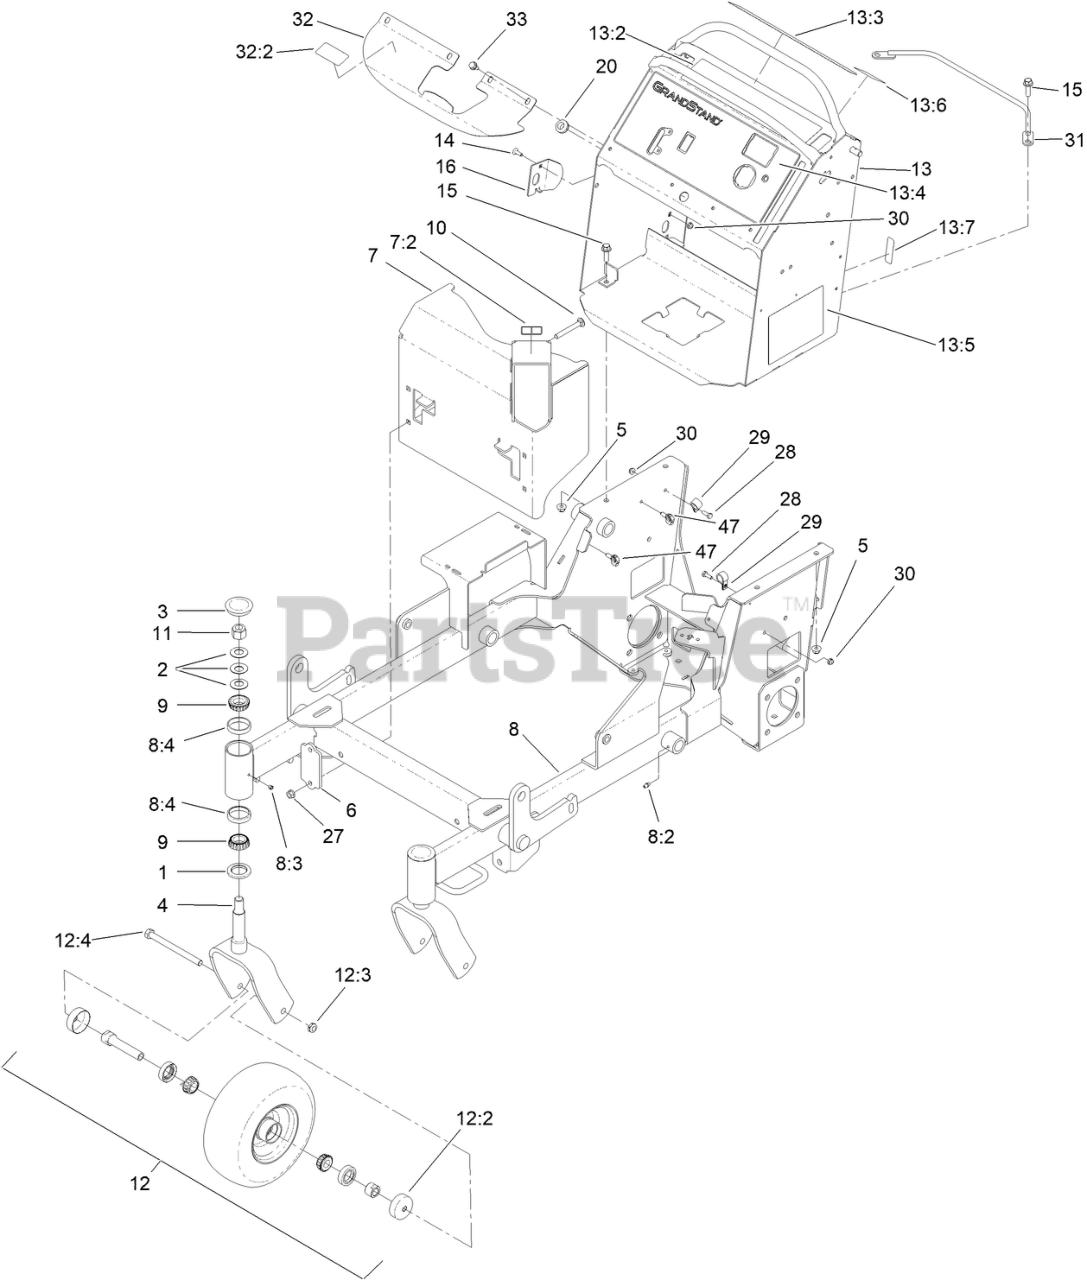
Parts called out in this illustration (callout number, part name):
1	SEAL-GREASE
2	WASHER-BELLVILLE
3	CAP-GREASE
4	FORK-CASTER
5	NUT-HF, NI
6	BRACKET-MOUNTING, GUARD
7	MUFFLER GUARD ASM
7:2	DECAL-WARNING
8	FRAME ASM
8:2	FITTING-GREASE
8:4	CUP-BEARING
9	BEARING-ROLLER, TAPERED
10	SCREW-CARR
11	NUT-LOCK, NI
12	WHEEL, TIRE AND BEARING ASM
12:2	GUARD-SEAL
12:3	NUT-HEX
12:4	SCREW-HH
13	TOWER - DECAL ASM
13:2	DECAL-OPC
13:3	DECAL-WARNING
13:4	DECAL - PANEL, CONTROL
13:5	DECAL-SERVICE AID, CE
13:6	DECAL-STABILITY, CE
13:7	DECAL - FUSE
14	BOLT-CARR
15	SCREW-HHF
16	PLATE-STRIKER
20	GROMMET
27	NUT-HF
28	SCREW-HH
29	CLAMP-CABLE
30	NUT-HF
31	RETAINER-CABLE
32	COVER-TANK
32:2	DECAL-FILL, FUEL
33	SCREW-HWHTF
47	CLIP-HARNESS
